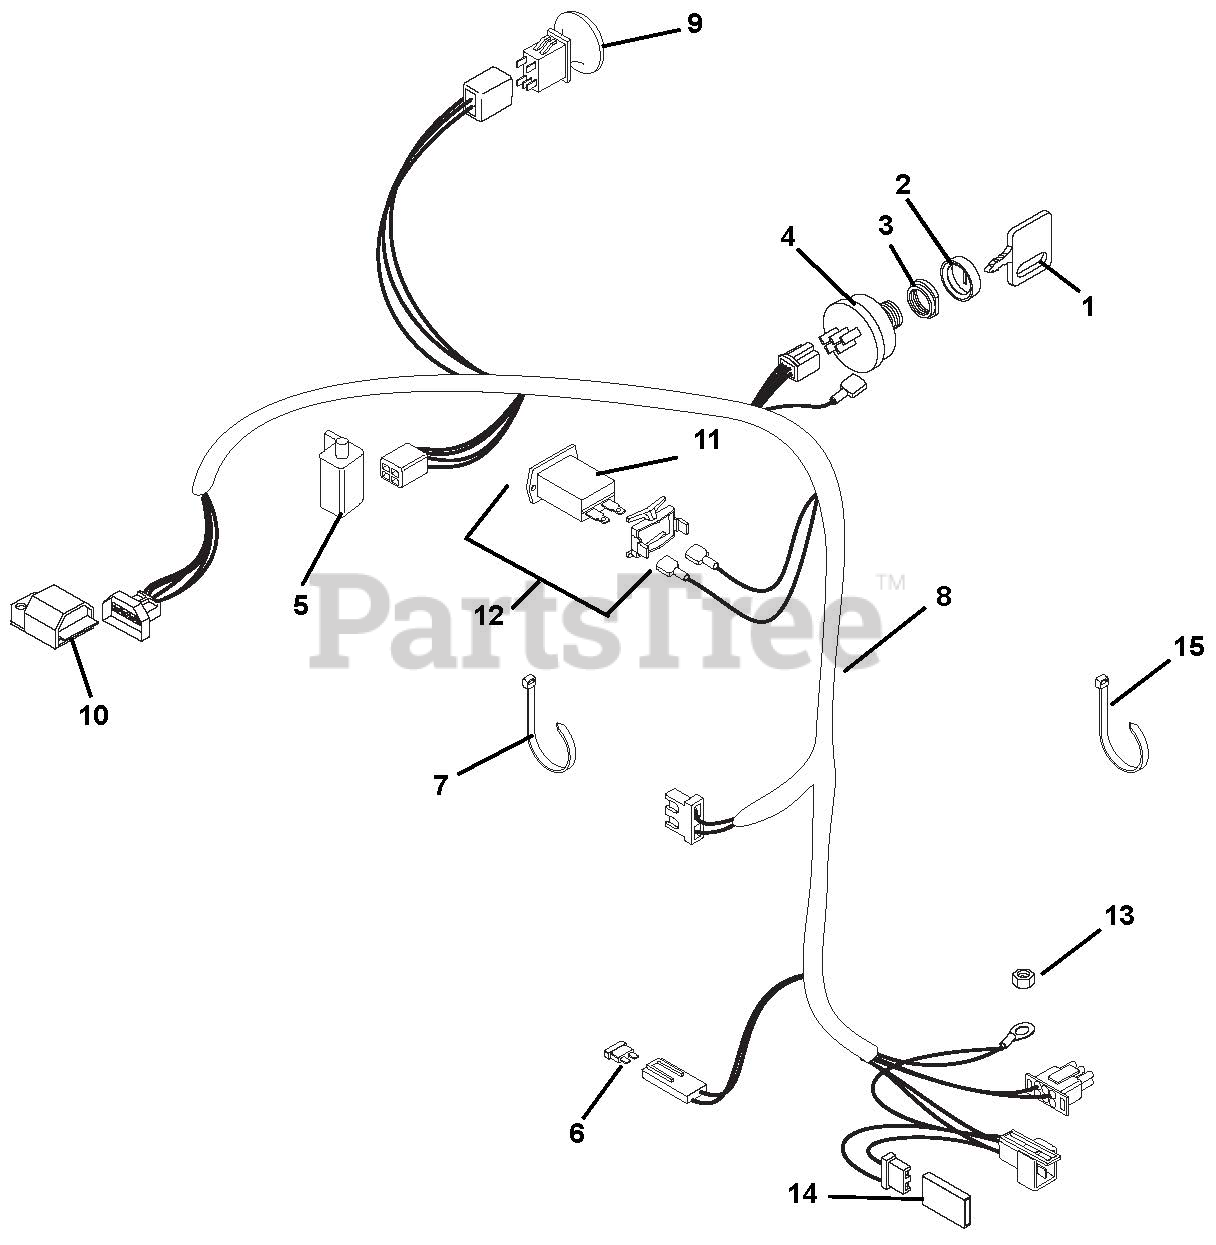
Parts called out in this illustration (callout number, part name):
1	Key- with Cap
2	Cap, Ignition Switch
3	Nut, Panel .562-24
4	Key Switch
5	Switch- Double Pole N.O./N.O.
6	Fuse-25 AMP
7	Tie Wrap-Black
8	Wire Harness, Gear Recoil
9	Switch, Clutch With Retainer
10	Module, Interlock Recoil
11	Hour Meter-Quartz
12	Kit, Hour Meter
13	Nut-Locking-Top-Flange .31-18
14	Diode, Connector Shell
15	Tie Wrap
